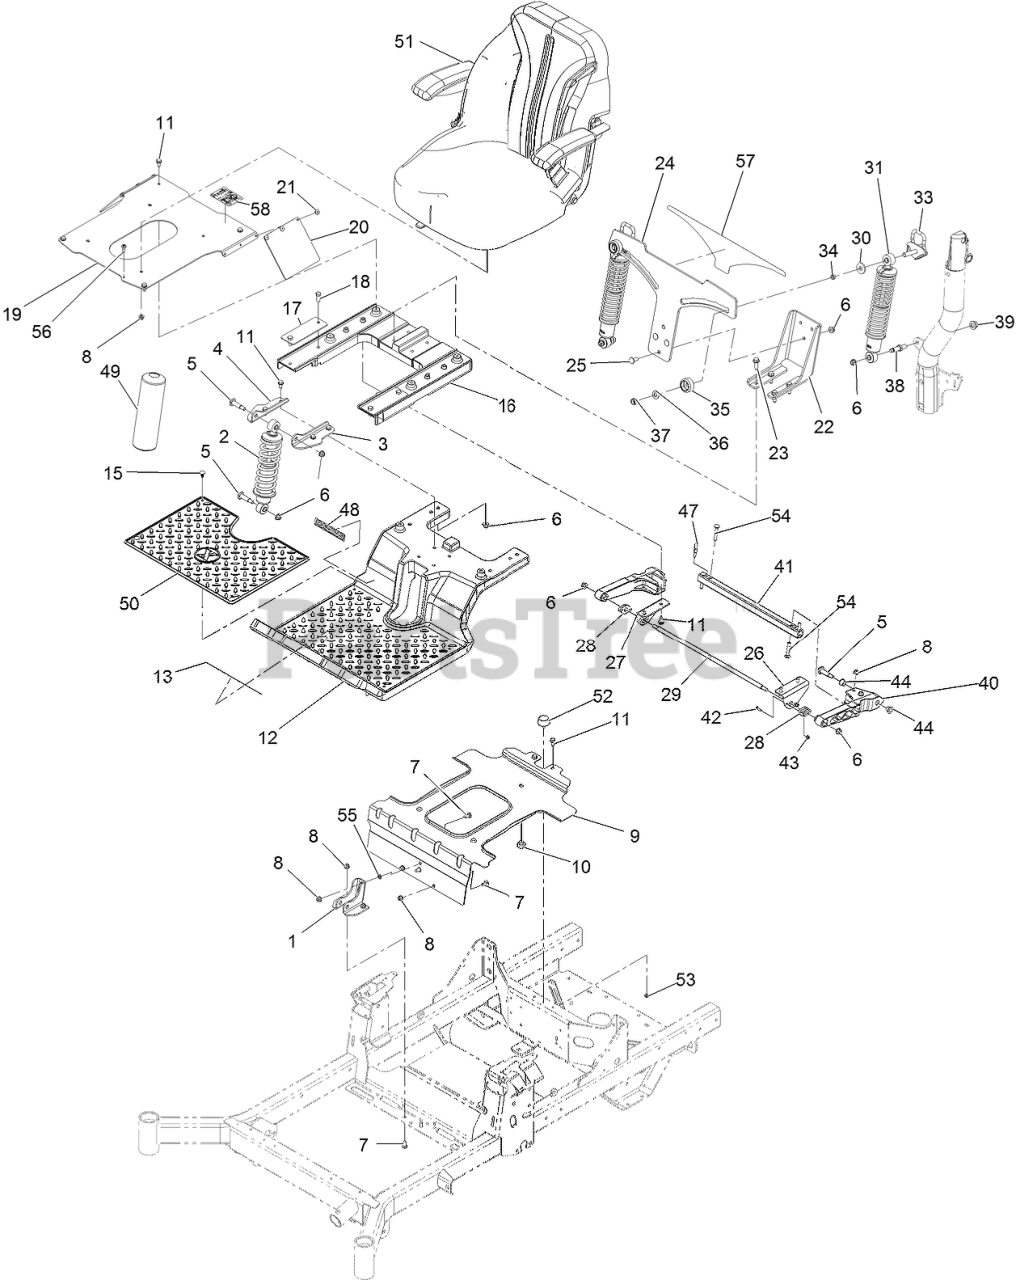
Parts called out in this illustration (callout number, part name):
1	BRACKET-SHOCK, FRONT LOWE
2	SHOCK/SPRING
3	BRACKET-SHOCK MOUNT, UPPE
4	BRACKET-SHOCK MOUNT, UPPE
5	BOLT-SHOULDER, HWH
6	NUT-HF, NI
7	SCREW-CARR
8	NUT-HF, NI
9	BRACKET-TANK
10	BUMPER-SEAT
11	Screw-HWH 5/16-18 X 3/4 Tf
12	SUBFRAME-FRONT
13	DECAL-DANGER
15	PLUG-PLASTIC
16	SUBFRAME-REAR
17	PLATE-BACKER
18	SCREW-HH
19	PLATE-SEAT
20	FLAP-RUBBER
21	RIVET-POP
22	BRACKET-MOUNT, LOWER
23	SCREW-THD
24	PLATE-MOUNTING, ADJ SHOCK
25	SCREW-CARR
26	BRACKET-ARM, TRAILING (LH
27	BRACKET-ARM, TRAILING (RH
28	BEARING-FLANGE
29	ROD-PIVOT
30	WASHER-PLASTIC
31	SHOCK/SPRING ASM
33	CAM LOCK ASM
34	BEARING-SLEEVE
35	KNOB-LOCK, CAM
36	WASHER-ADJUSTING
37	NUT-HEX
38	BOLT-SHOULDER
39	Nut-Lock 1/2-13
40	TRAILING ARM
41	TUBE-ARM, TRAILING
42	SCREW-CARR
44	BUSHING-FLANGE
47	CLAMP-HOSE
48	DECAL-RADIUS LOGO
49	COVER-SHOCK
50	FLOOR MAT
51	ASM-SEAT EXMARK
54	BOLT-CARR
55	NUT-PUSH
56	SCREW-SHOULDER
57	DECAL-ADJUSTMENT, RIDE
58	DECAL-AID, SERVICE
